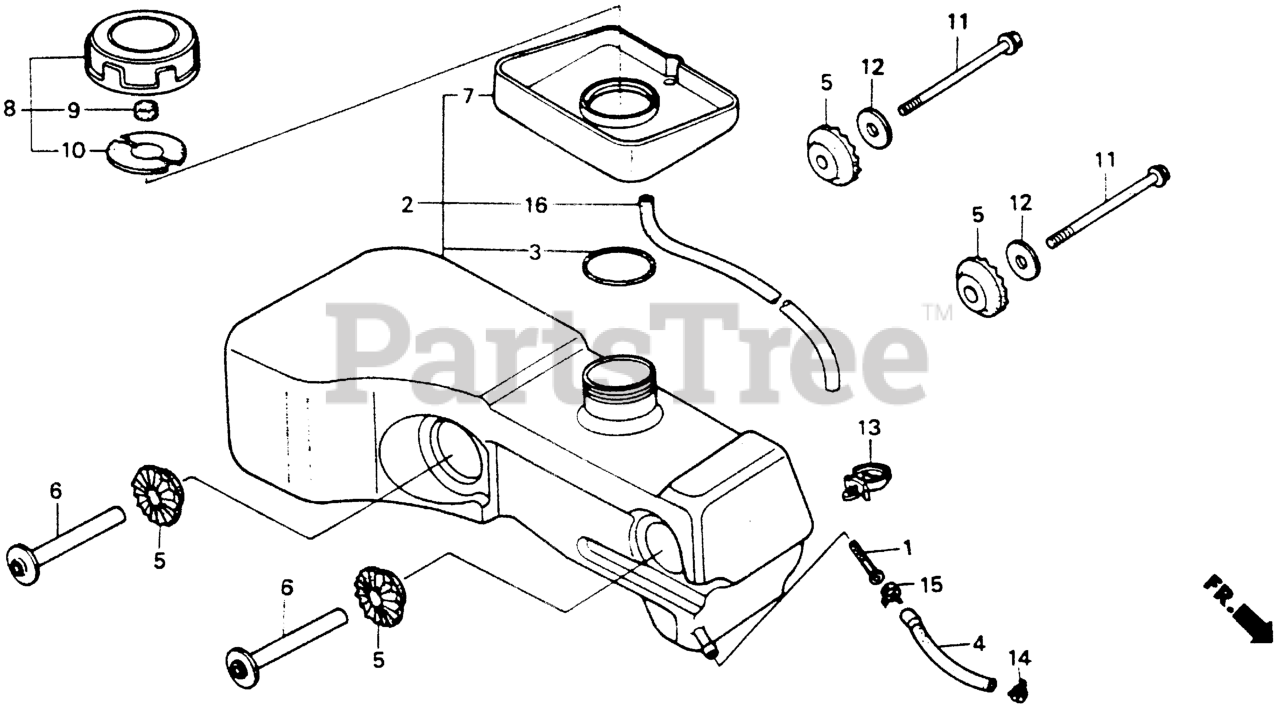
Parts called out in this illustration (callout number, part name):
1	FILTER, FUEL
2	TANK, FUEL
2	TANK, FUEL (NOT AVAILABLE)
3	O-RING (49.5X3.1)
4	TUBE, FUEL
5	RUBBER, TANK MOUNTING (NOT AVAILABLE)
6	COLLAR, TANK SETTING
7	TRAY, FUEL
8	CAP ASSY., FUEL TANK
9	SPONGE, FUEL CAP BREATHER
10	GASKET, FUEL CAP
11	BOLT, FLANGE (8X110) (NOT AVAILABLE)
12	WASHER, TANK COLLAR
13	CLIP, WIRE HARNESS
14	CLIP, TUBE (D8)
15	CLAMP, TUBE (D10)
16	BULK HOSE, VACUUM (12X1000) (12X340)
